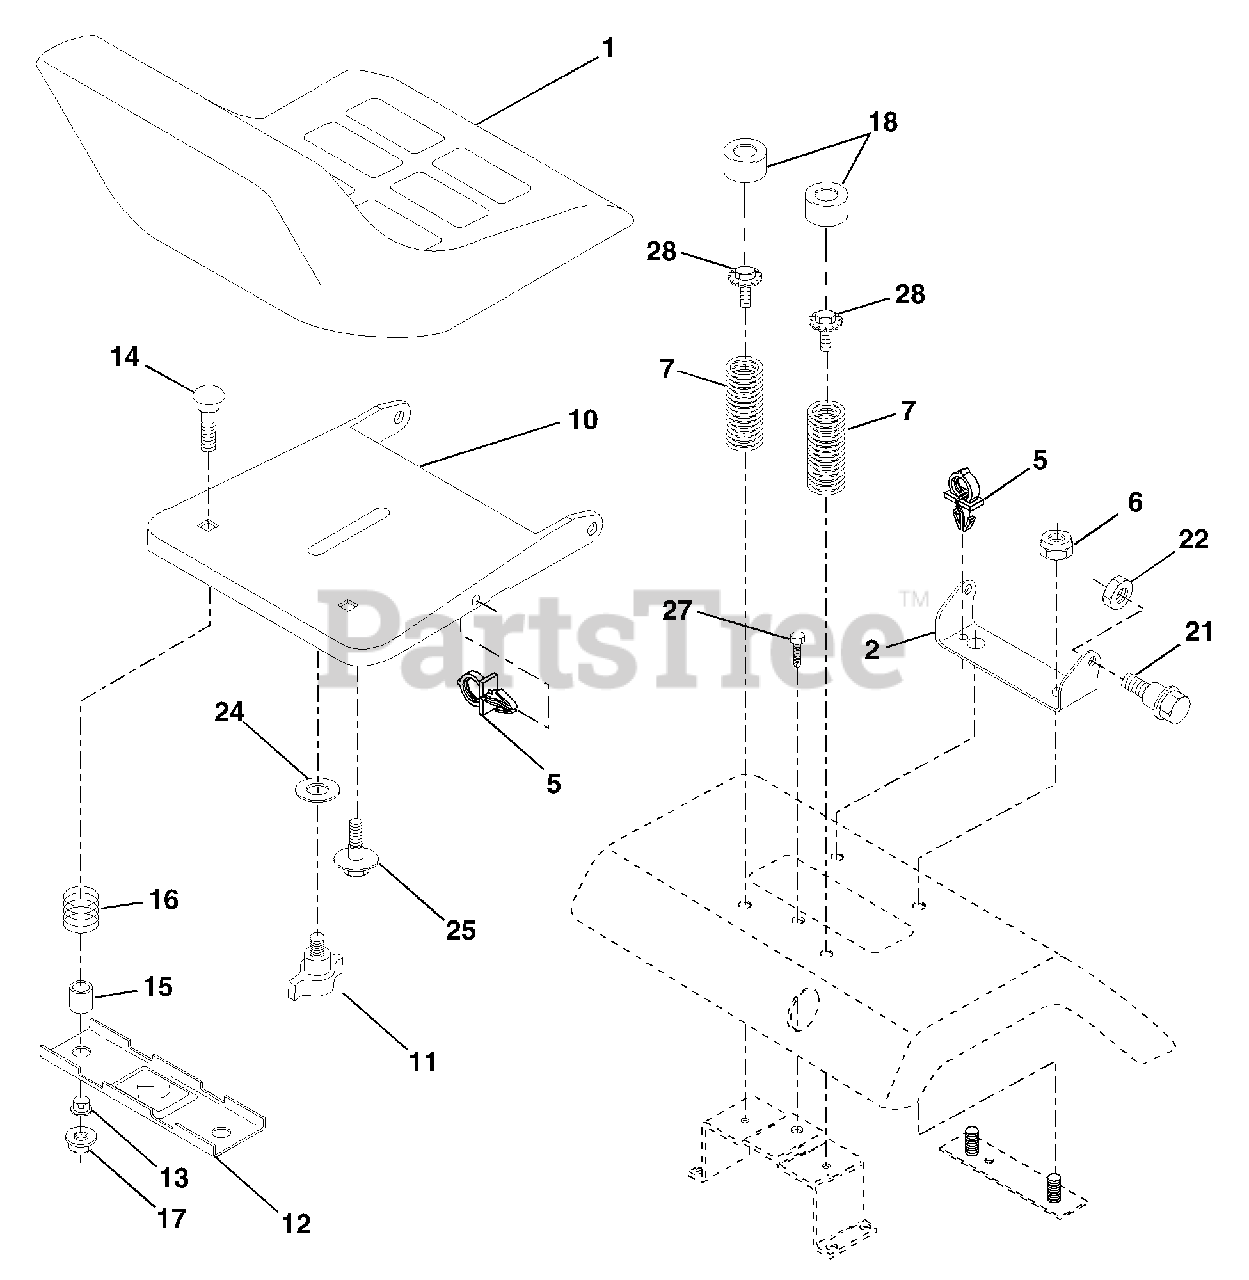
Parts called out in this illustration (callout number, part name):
1	Seat
2	Pivot Bracket, Seat
5	Clip, Push-in Hinged
6	Nut, Lock Hex w/Ins 3/8-16 UNC
7	Spring, Seat
10	Pan, Seat
11	Knob, Seat, Black
12	Bracket, Switch Mounting
13	Bushing, Snap, Black, Nylon
14	Bolt, Carriage 1/4-20 x 1-1/2
15	Spacer, Split .28 x .96
16	Spring
17	Locknut, Flange 1/4 Grade 5
18	Cap Spring Seat Blk 1.75 x 1.0
21	Bolt, Shoulder 5/16-18 Unc -2A
22	Nut Lock Hex W/Ins 5/16-18 Unc
24	Washer 17/32 x 1-3/16 x 12 Gauge
25	Bolt, Shoulder 5/16-18 x .62
27	Screw Thdrol 3/8-16 x 3/4
28	Bolt 5/16-18 UNC x 3/4 w/Sems
